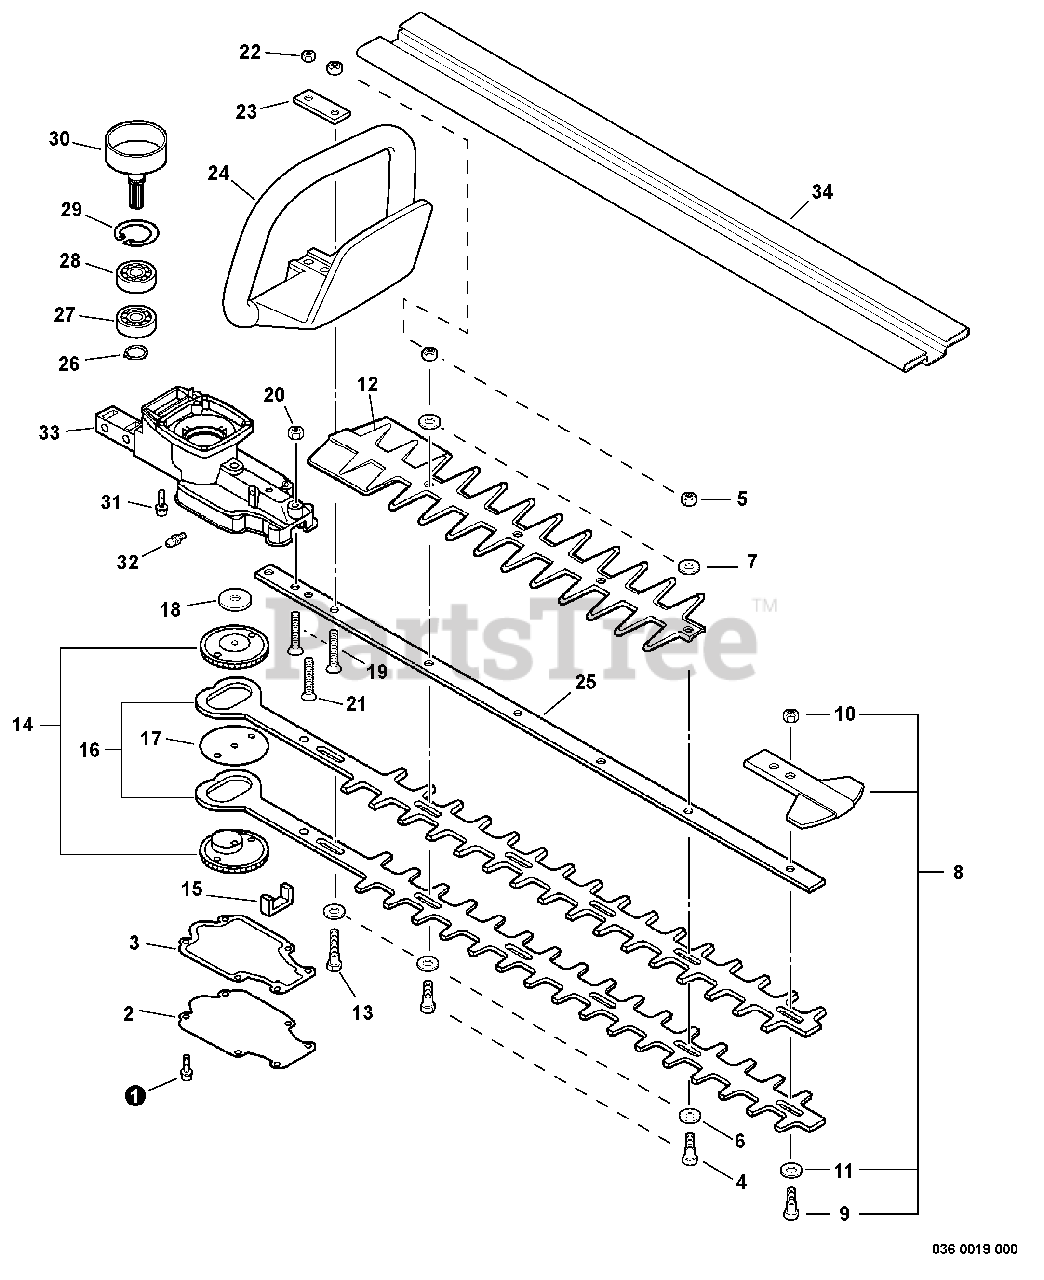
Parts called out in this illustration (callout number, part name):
1	BOLT 4×12
2	COVER, GEAR CASE
3	GASKET, GEAR CASE
4	BOLT 6×18
6	WASHER 6.5×15.5×0.6
7	WASHER 6.5×15.5×0.6
8	TIP GUARD KIT
9	BOLT 6×20
11	WASHER 6.5×15.5×0.6
12	GUARD, CUTTER BLADE
13	BOLT M6×35
14	GEAR, SPUR
16	CUTTER
17	WASHER 6.7×54×0.38
18	WASHER 6.5×30×0.2
19	SCREW 6×30
20	NUT, HEX M6
21	SCREW 5×30
22	NUT, LOCK M5
23	PLATE, EYE
24	HANDLE, SUPPORT
25	SUPPORT, BLADE
26	RING, SNAP 14
27	BEARING, BALL 6202
28	BEARING, BALL 6202
29	RING, SNAP 35
30	DRUM, CLUTCH
31	BOLT 4×16
32	FITTING, GREASE
33	CASE, GEAR
34	SCABBARD 23.6"
